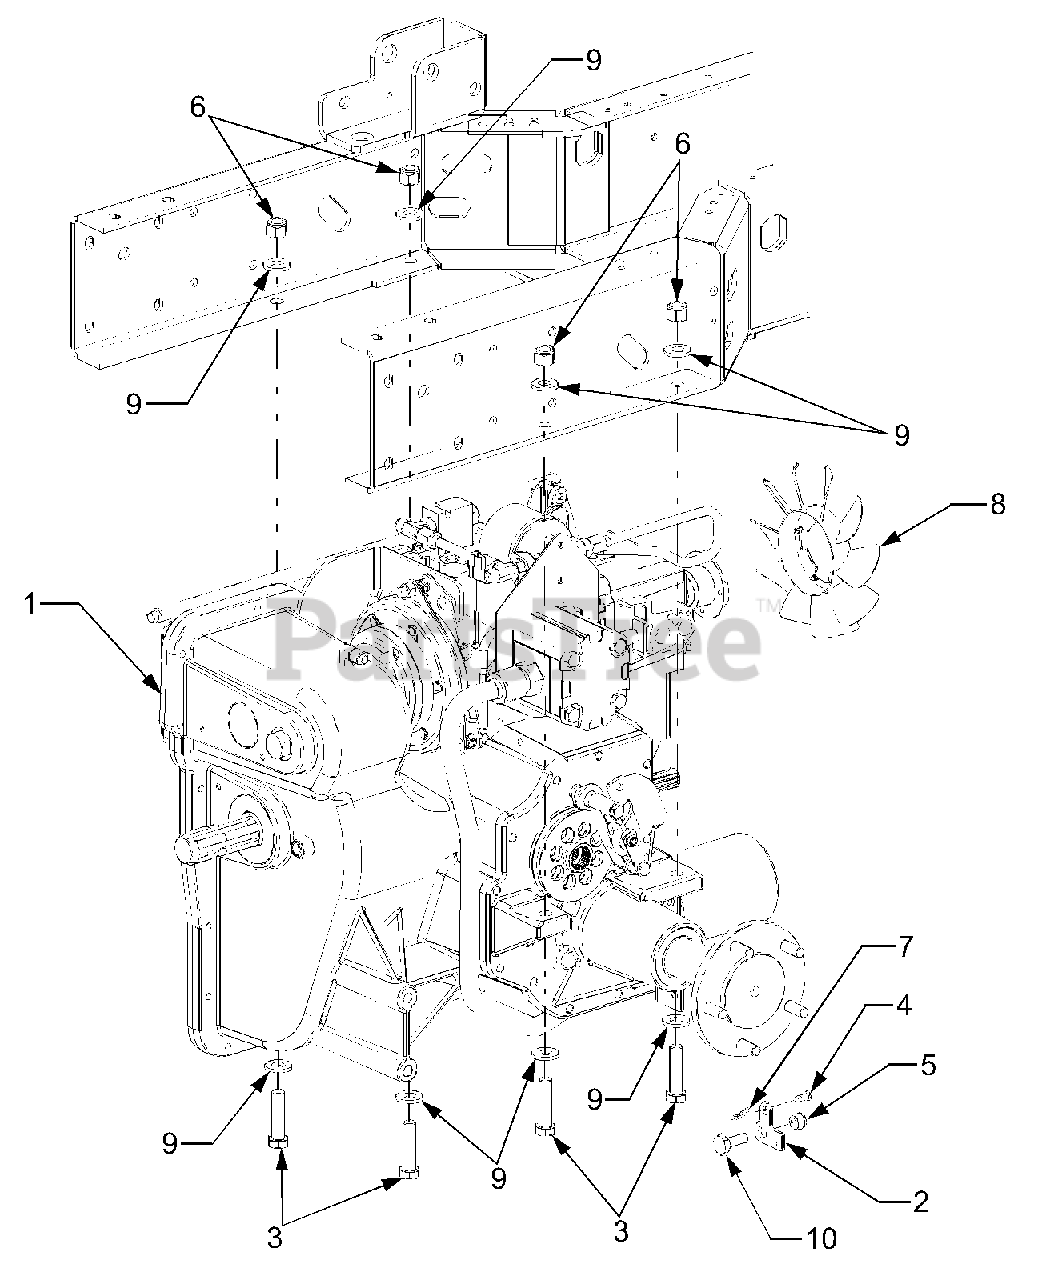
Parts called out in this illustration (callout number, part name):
1	Transmission Assembly
2	Link, Diff Lock Actuator
3	Screw, Hex Cap 1/2-13 x 2.0 GR8
4	Pin, Clevis, .25 x .50
5	Nut. Hex Insert Lock, 3/8-24
6	Nut, Hex Insert Lock, 1/2-13
7	Pin, Internal Cotter
8	Fan, Transmission Cooling
9	Washer, Flat, .531 x .1062 x .134
10	Screw, Shoulder, 1/2 Dia. x .180
